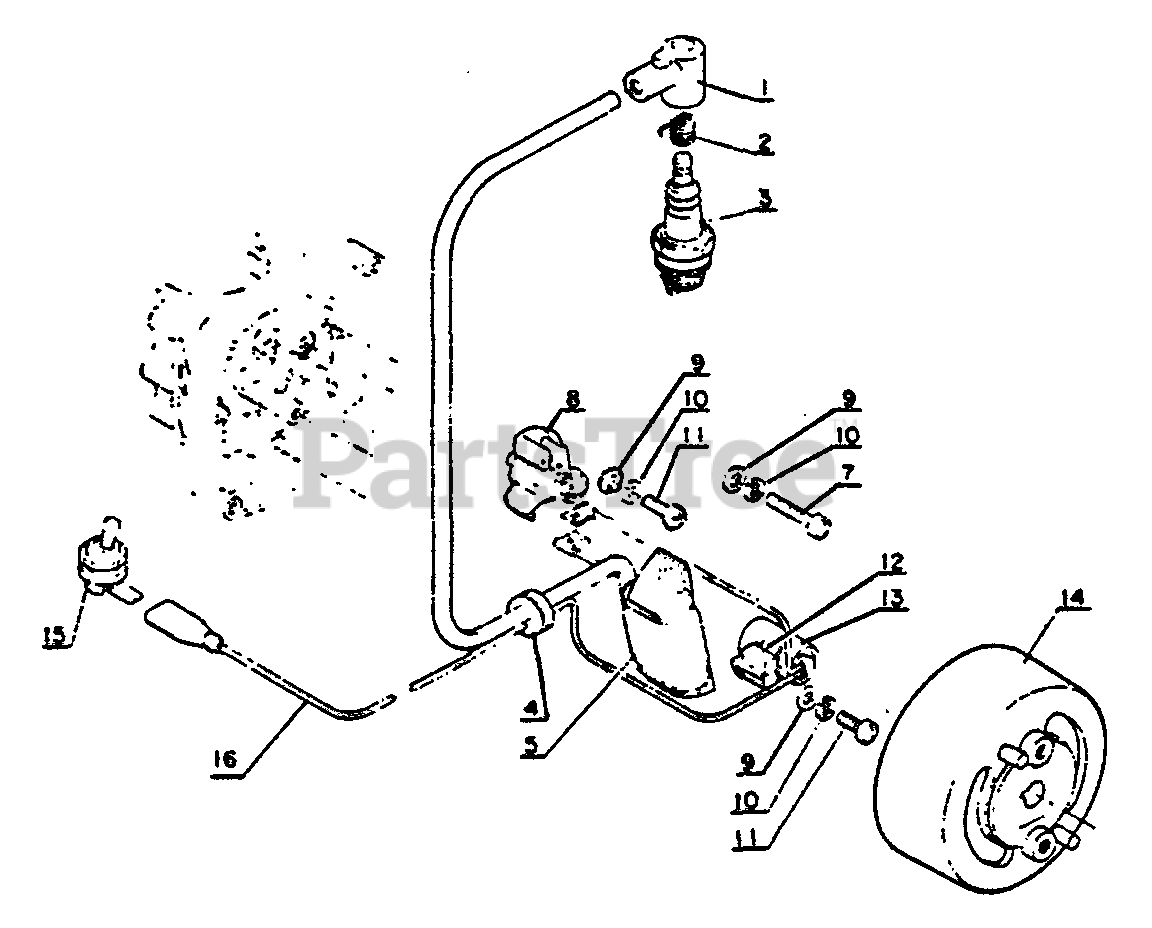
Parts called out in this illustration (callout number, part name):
1	CAP, SPARK PLUG
2	TERMINAL, SPARK PLUG CAP
3	SPARK PLUG - BM6A
5	COIL, IGNITION
7	SCREW 4×25
8	CONTACT POINT SET
9	WASHER 4 MM
10	WASHER, SPRING 4 MM
11	SCREW 4×10
12	PAD, OIL
13	CONDENSER
14	FLYWHEEL
15	SWITCH, IGNITION
16	LEAD - GROUND
